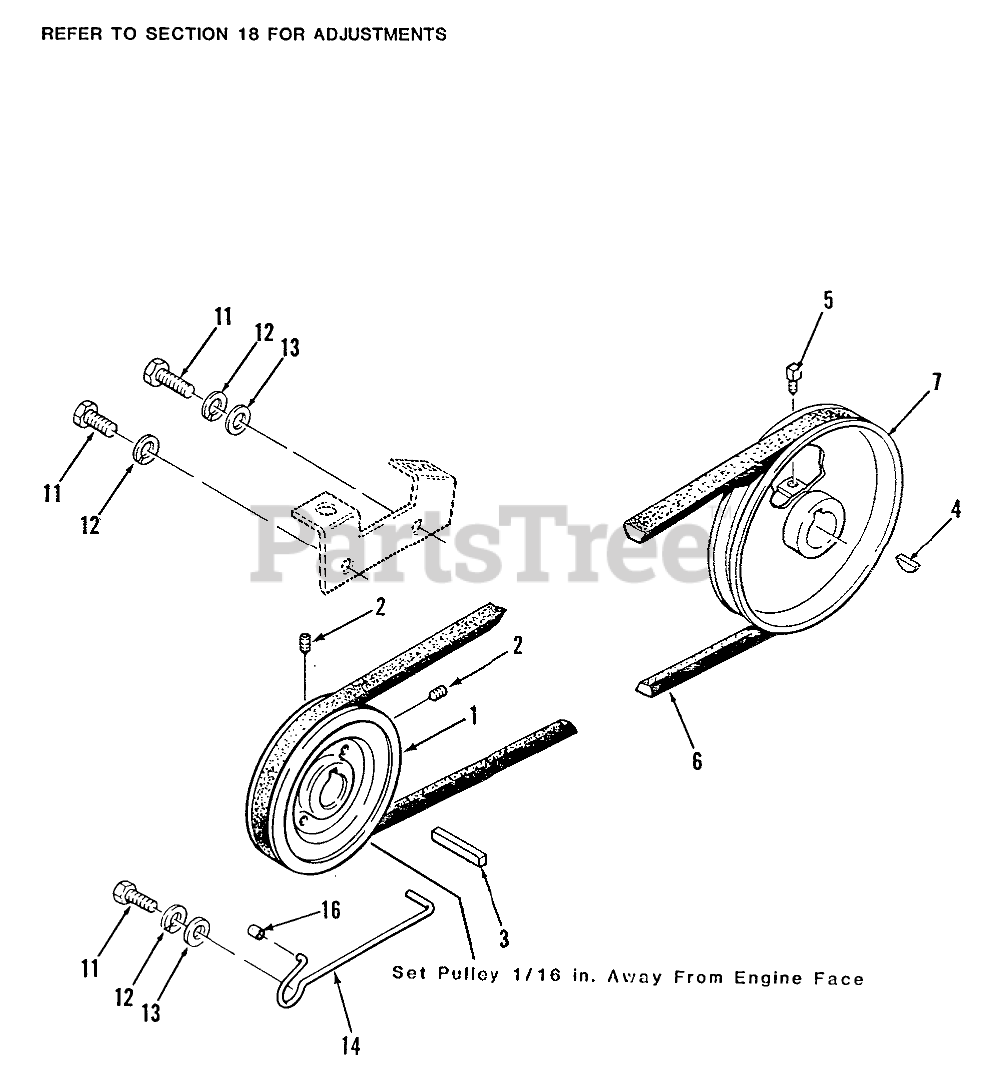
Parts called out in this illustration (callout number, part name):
1	PULLEY
2	Set Screw
4	KEY-HI PRO
5	Set Screw
6	V BELT
7	PULLEY-TRANSMISSION
11	7/16-14 x 1 1/4 Bolt
12	LOCKWASHER
13	WASHER
14	GUIDE-BELT BOTTOM
